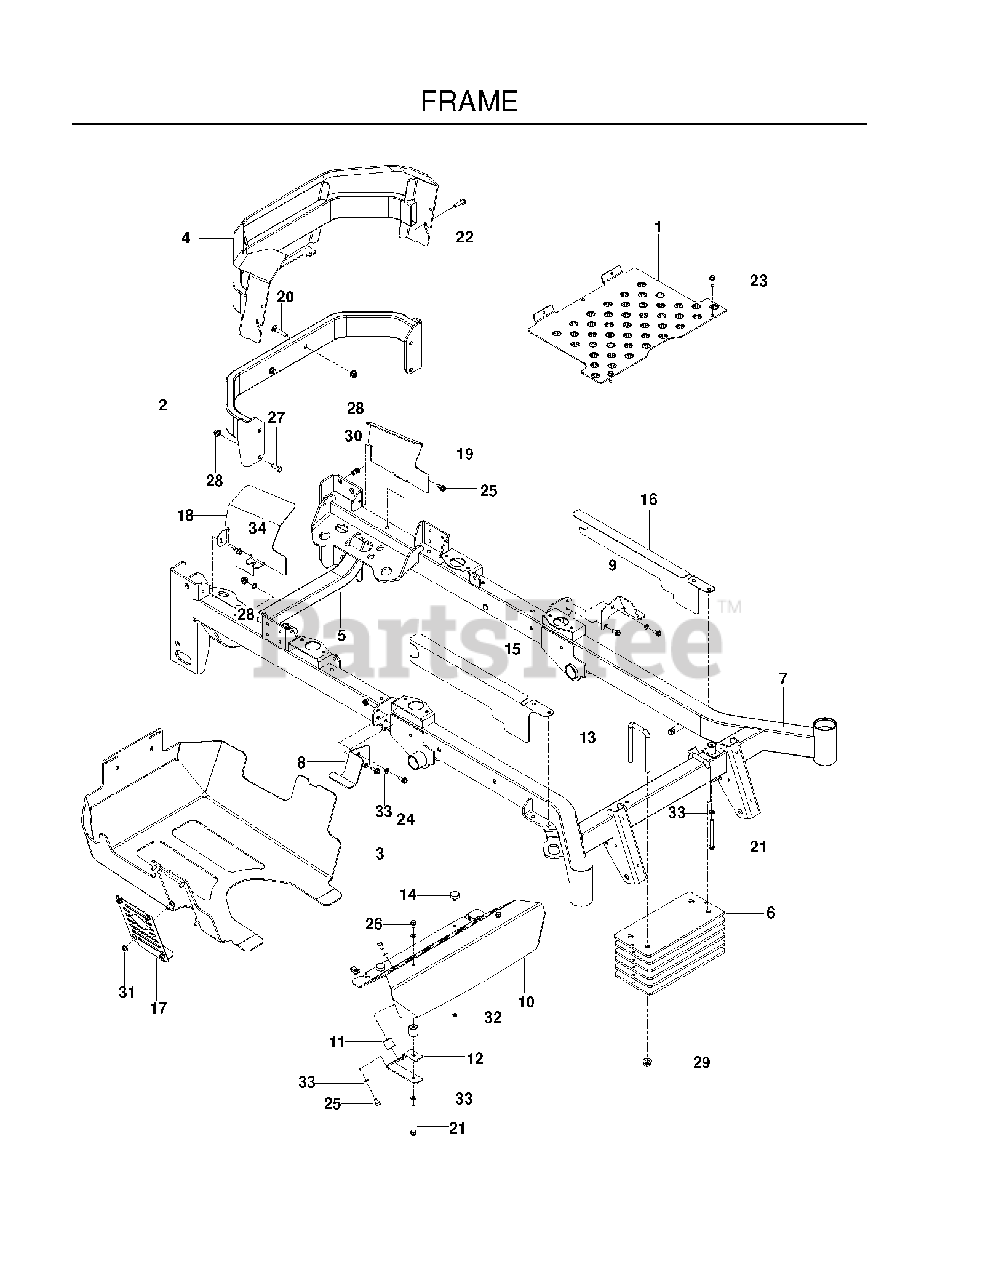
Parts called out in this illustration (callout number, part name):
1	PLATE, FLOOR PAN, OR
2	BUMPER, REAR, ORG
3	SKID.PLATE.GRAY
4	GUARD.REAR.GRAY.ZTR
5	CROSS MEMBER, GRAY
6	PLATE, WEIGHT BLK
7	FRAME.DIESEL.ORANGE
8	MOUNT, TANK, RT-BLK
9	MOUNT, TANK, LT-BLK
10	PLATE, FOOT REST, OR
11	MOUNT, F/F INSERT
12	BRACKET, REST MOUNT
13	LINKAGE, U-BOLT
14	GROMMET, BUMPER
15	SKIRT.RH.BLK
16	SKIRT.LH.BLK
17	PANEL.ACCESS.GRAY
19	GUARD.LT.REAR.GRAY
20	RHSNB 3/8C X 2
21	HHFS 5/16-18 X 3 3/4
22	HHFS 5/16-18 X 1.25 TPBLT GD 5
23	RP BLT 5/16-18 X 1 THRD FORM D
24	HHFS 5/16-18 X 3/4
25	BOLT 5/16-18 X 3/4
26	SCR 5/16-18 X 1/2 SELFTAP ZN
27	HCS 3/8-16X1.GRD.5.ZD
28	NUT 3/8-16 HEX FLG NYLOC ZD
29	NUT, 1/2-13 HEX FLG NYLOC ZD
30	NUTSERT 5/16-18 THICK GRIP
31	5/16-18 NYLOC FLANGE NUT
32	JAM NUT 1/4C (2 2 PW01)
33	WASH 5/16 DISC SPRING ZD
34	WASHER 3/8 EXT STAR ZD
